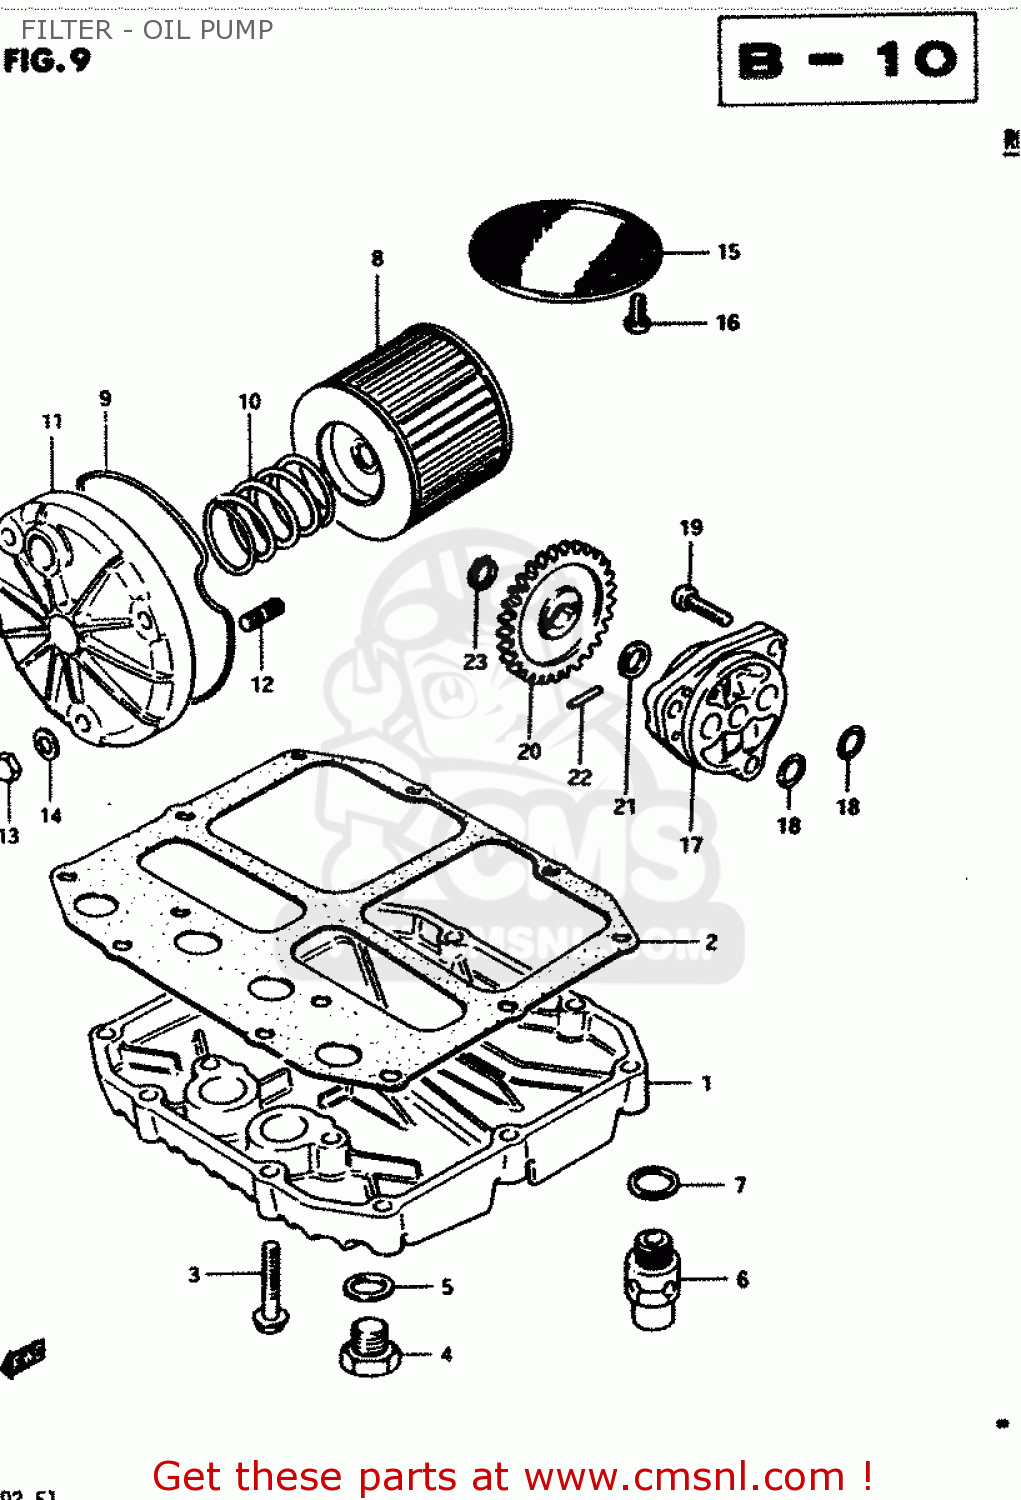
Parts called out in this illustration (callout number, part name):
1	PAN,OIL
2	GASKET,OIL PAN (MCA)
3	BOLT
4	PLUG
5	GASKET(14X19.2X2) (NAS)
6	REGULATOR ASSEMBLY,ENGINE
7	WASHER
8	FILTER ASSY,ENGINE OIL
9	O RING,OIL FILTER CHAMBER CAP
10	SPRING
11	CAP,OIL FILTER
12	STUD 6X20
13	NUT
14	WASHER
15	STRAINER,ENGINE OIL
16	SCREW 6X12
17	PUMP ASSY,ENGINE OIL
18	O RING(D:1.9,ID:13)
19	SCREW
20	GEAR,OIL PUMP DRIVEN
21	SHIM
22	PIN(4X15.8)
23	CIRCLIP
